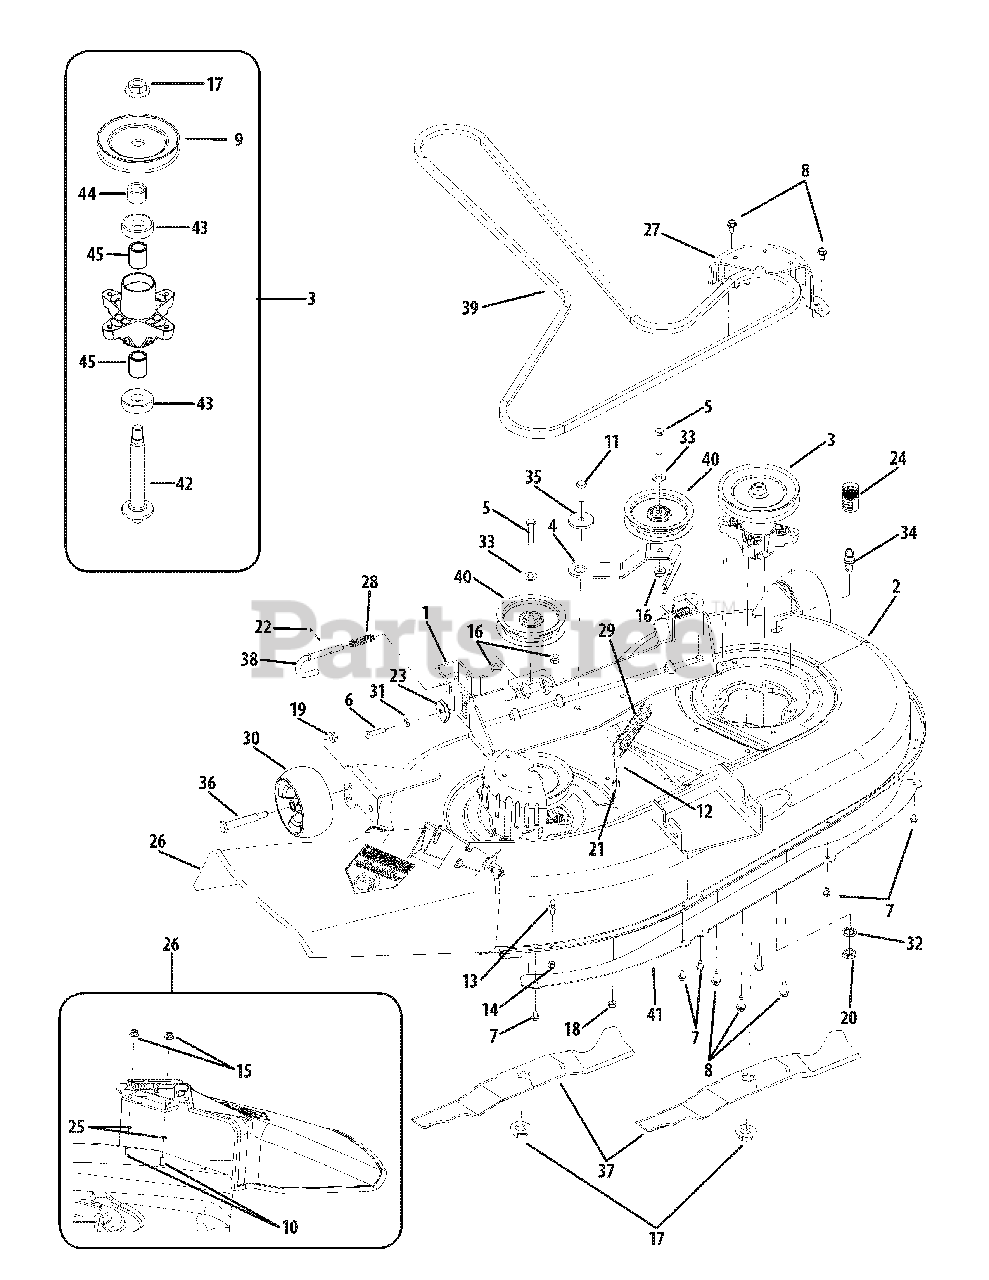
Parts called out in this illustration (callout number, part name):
1	Deck Lift Bracket
2	Deck Housing
3	Spindle Assembly
4	Idler Arm
5	Hex Cap Screw, 3/8-16 x 1.75
6	Hex Cap Screw, 5/16-18 x 1.25
7	Hex Washer Screw, 1/4-20 x .5
8	Hex Washer Screw, 5/16-18 x .750
9	Deck Pulley, 6.3 Dia
10	Hex Cap Screw, 1/4-20 x .62
11	Hex Cap Screw, 3/8-16 x 1.25
12	Hex Cap Screw, 5/16-18 x 1.75
13	Grass Catcher Pin, 1/4-20
14	Hex Insert Lock Nut, 1/4-20
15	Hex Insert Flange Lock Nut, 1/4-20
16	Hex Insert Flange Lock Nut, 3/8-16
17	Hex Flange Nut, 5/8-18
18	Hex Insert Lock, 5/16-18
19	Hex Flange Lock Nut, 3/8-16
20	Hex Nut, M16-1.5
21	Hex Nut, 5/16-18
22	Cotter Pin, 1/8 x 1.25
23	Deck Adjustment Gear
24	Water Nozzle Adapter
25	Push Nut, .25 x .5
26	Discharge Chute Assembly
27	Belt Cover
28	Compression Spring, .535 x 1.751
29	Extension Spring, .94 Dia. x 6.74
30	Deck Ball Wheel, 5.0
31	Lock Washer, 5/16
32	Lock Washer
33	Flat Washer, .38 x .93 x .11
34	Deck Water Nozzle
35	Shoulder Spacer, .884 x .19
36	Shoulder Screw, .5 x 2.5 x 3/8-16
37	Blade, 3 in 1, 21.23
38	Deck Hanger Rod
39	V-Belt
40	Idler Pulley, 4.25 Dia
41	Deck Skirt
42	Spindle Shaft, 5.75
43	Ball Bearing
44	Spacer, .820 x 1.15 x .73
45	Spacer, .8 x 1.10 x 1.322
